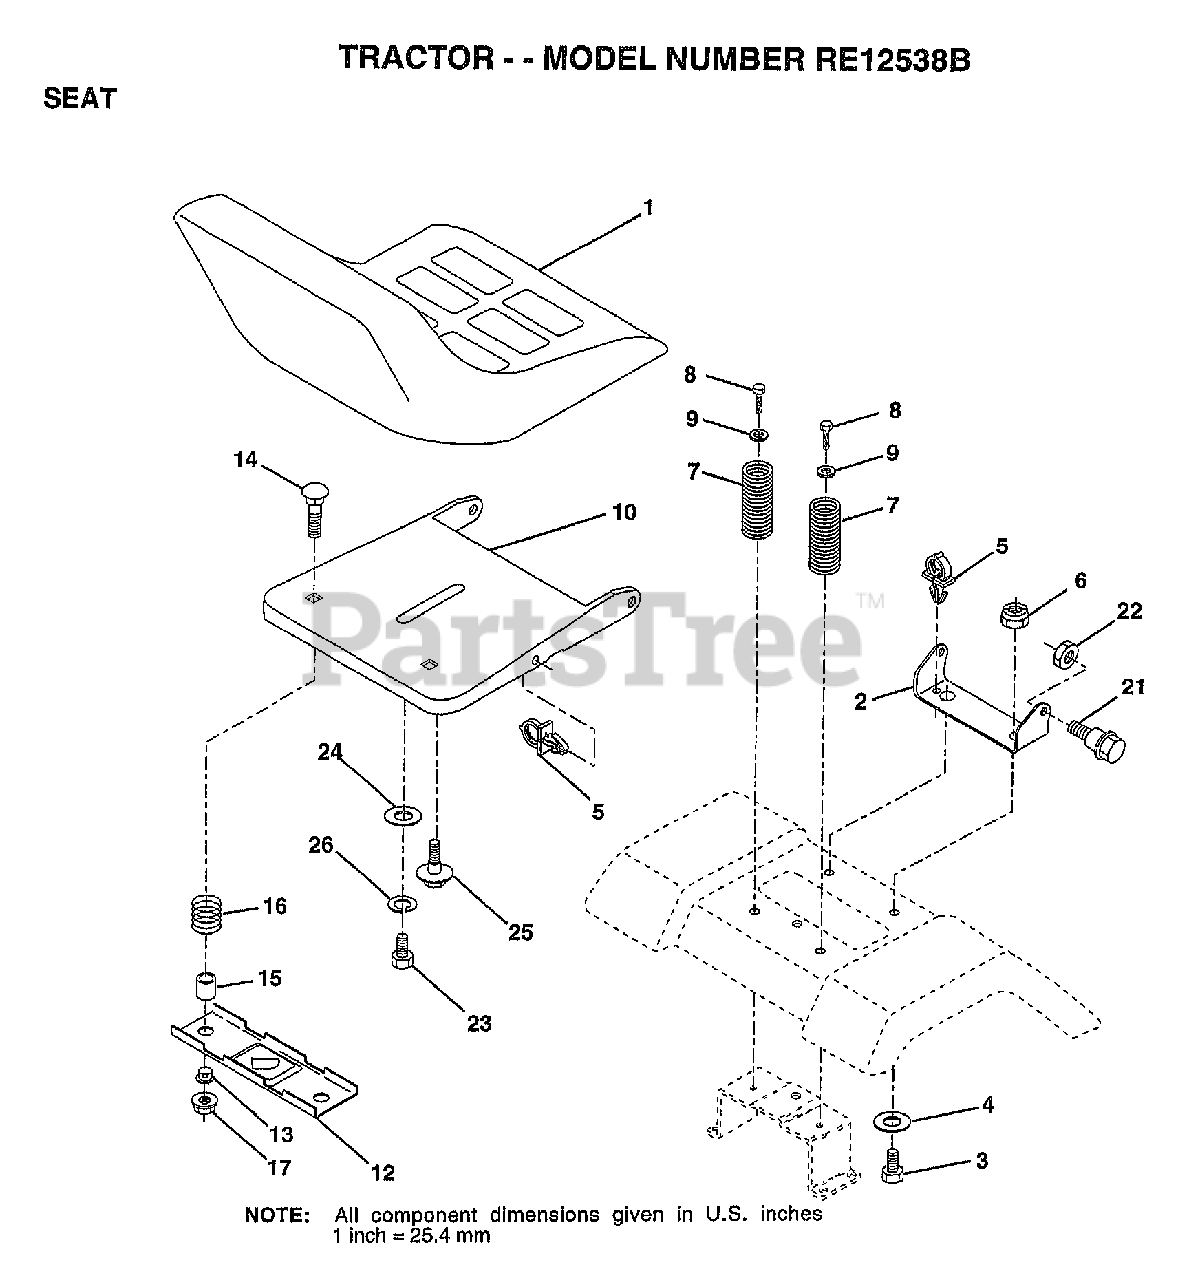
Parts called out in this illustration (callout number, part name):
2	BRACKET PVT SEAT
3	BOLT
4	WASHER PM
5	CLIP.PUSH-IN.HING
6	NUT
7	SPRING COMPRESSIO
8	SCREW GTV
9	WASHER
10	PAN-SEAT
12	BRKT SWITCH
13	BUSHING
14	BOLT-RD HD SQ NK
15	SPLIT SPACER
16	SPRING
21	"BOLT,SHOULDER"
22	NUT
23	BOLT
24	WASHER
25	"BOLT,SHOULDER"
26	LOCKWASHER
